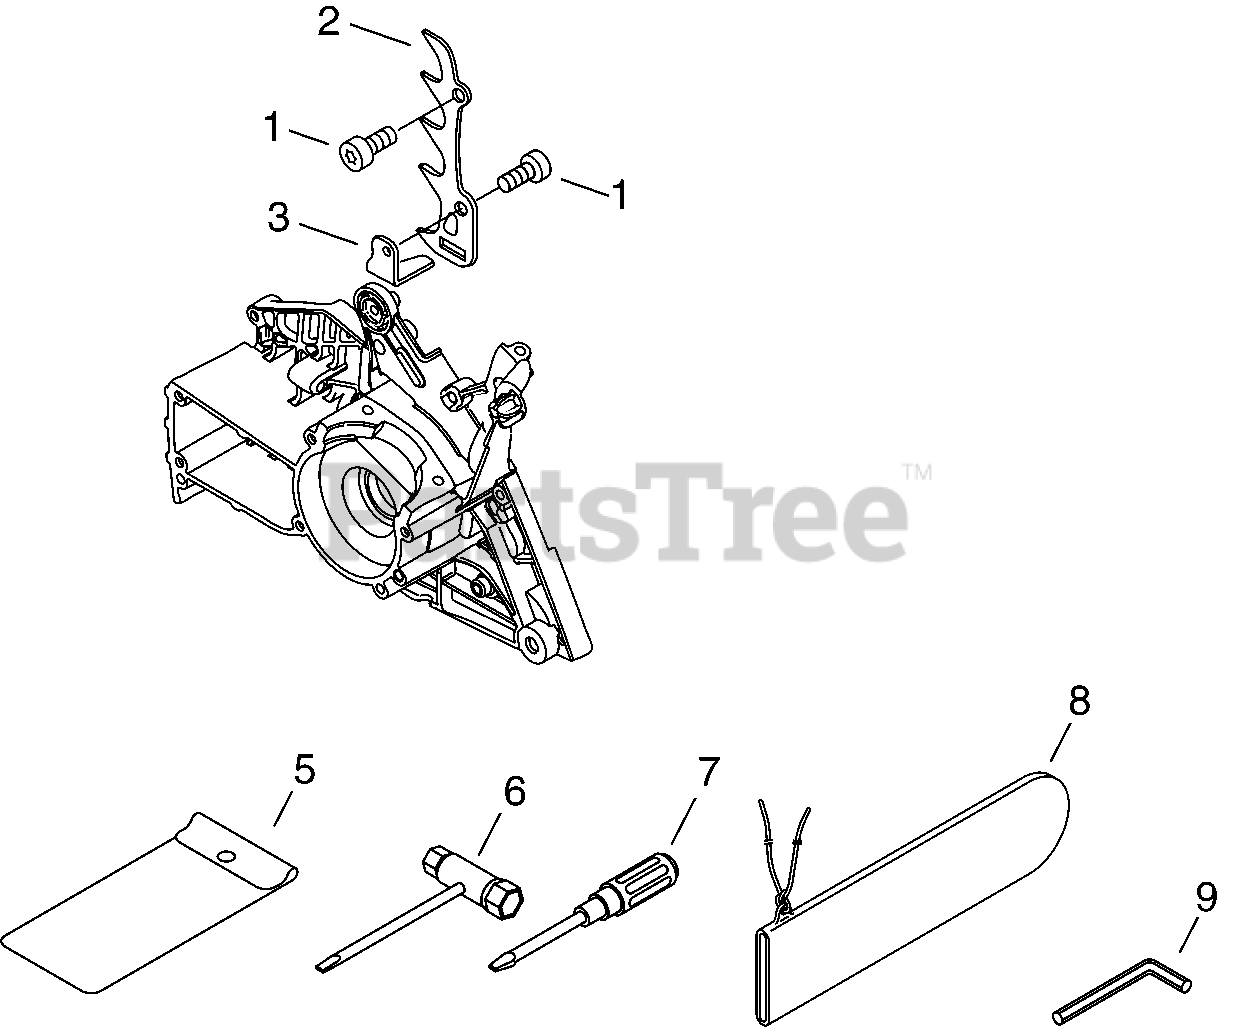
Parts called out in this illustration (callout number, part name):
1	BOLT, TORX 5×16
2	SPIKE, BUMPER
3	CHAIN CATCHER
5	BAG, TOOL
6	T-WRENCH 13×19 L= 180
7	SCREWDRIVER 50MM
8	SCABBARD
9	WRENCH, ALLEN
